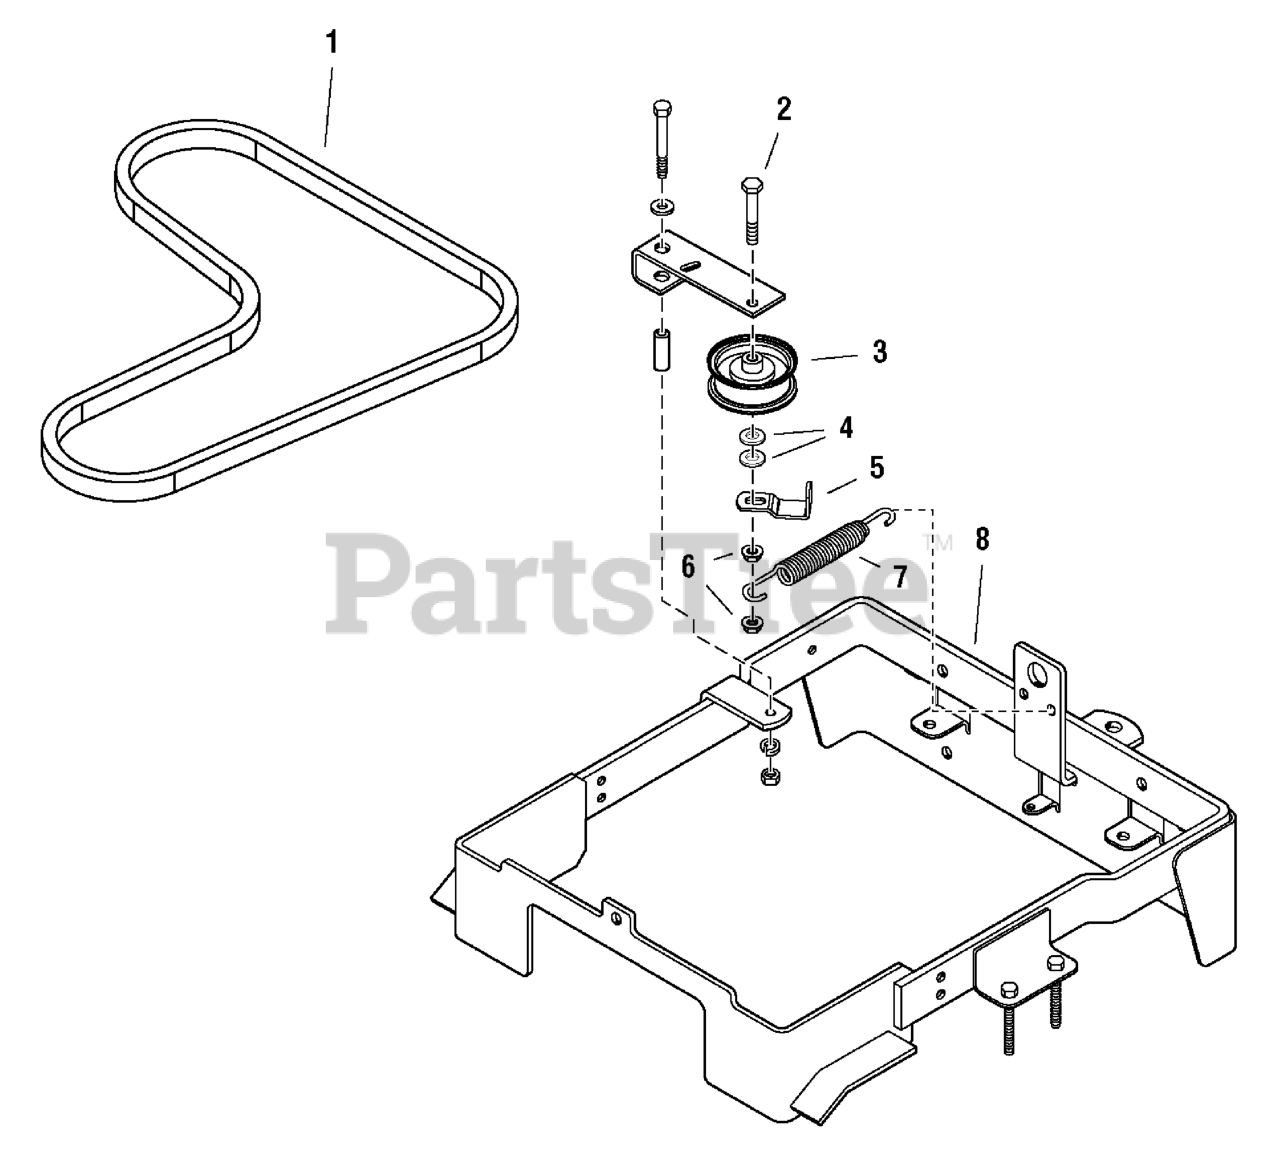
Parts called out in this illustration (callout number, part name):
2	Capscrew, Hex, 3/8-16 x 2-1/2
3	PULLEY, Idler
4	WASHERS, Flat
5	BELT GUIDE
6	NUT, Nylock, 3/8-16
7	SPRING, Extension
8	CARRIER, Transmission
